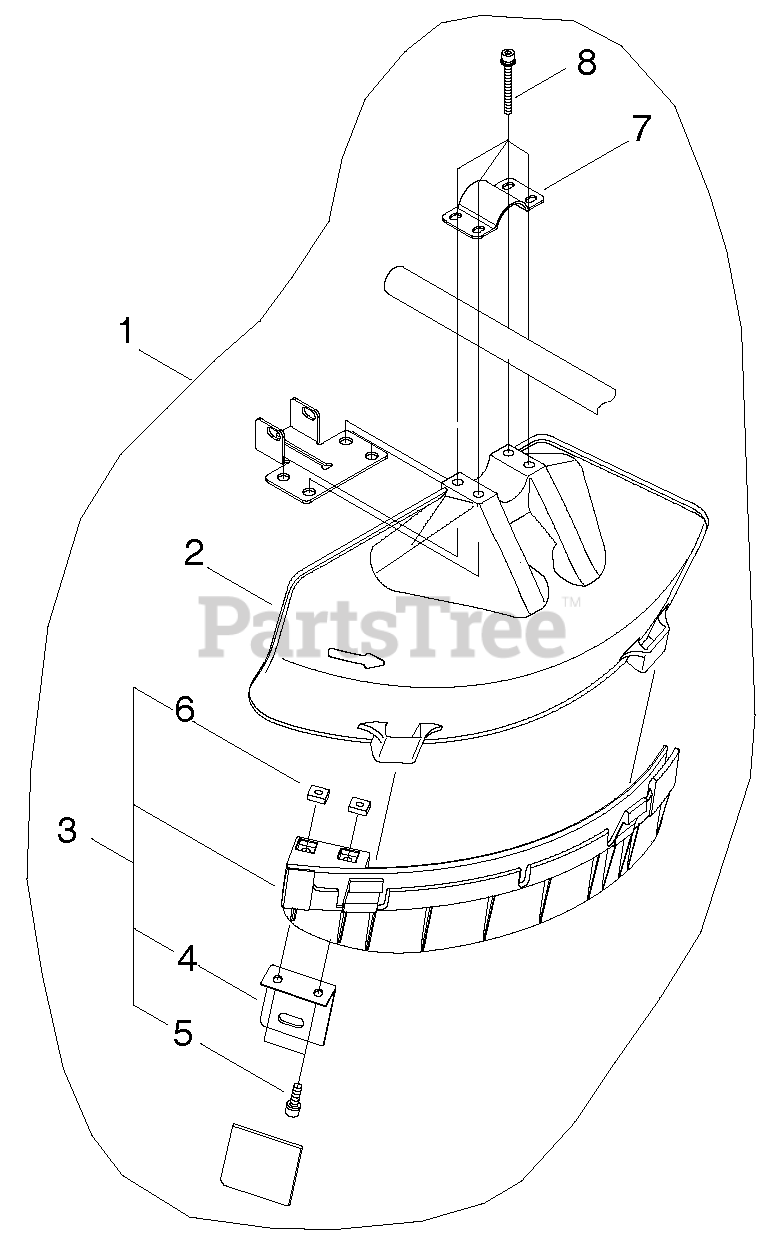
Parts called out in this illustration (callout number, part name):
1	DEBRIS SHIELD KIT
2	SHIELD, DEBRIS PLASTIC
3	DEBRIS SHIELD EXTENSION ASSY
4	CUTTER
5	BOLT M5×16
6	NUT M5
7	CLAMP, UPPER
8	BOLT M5×45
